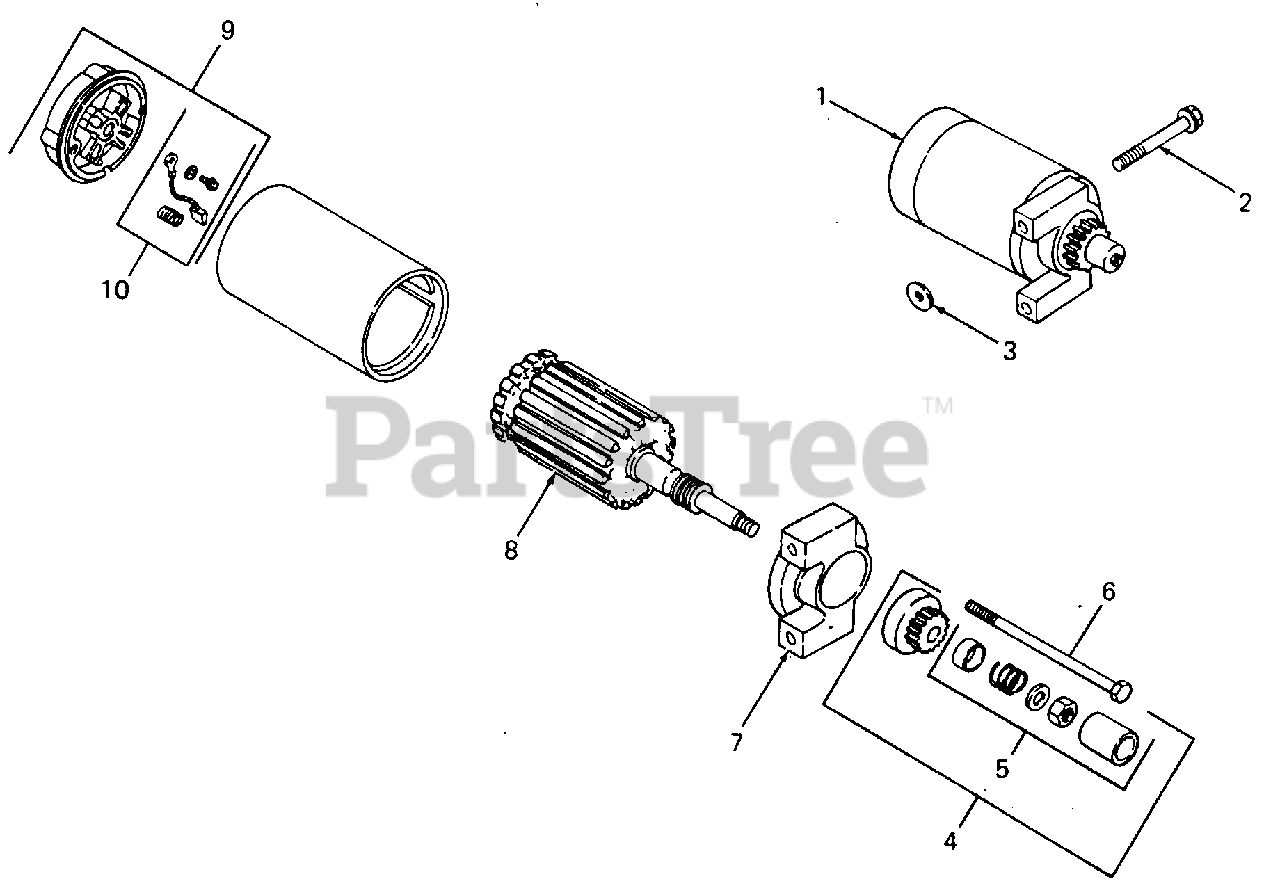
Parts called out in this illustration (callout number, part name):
1	Starter, Bendix Assy
2	Screw, Bendix Starter, M8 X 1.25 X 65.5
3	Washer, Flat
4	Kit, Drive
5	Kit, Drive Parts
6	Screw, Hex Flange, 1/4-20 X 4-1/4
7	Cap, Drive End
9	Cap, Commutator End
10	Kit, Brush
